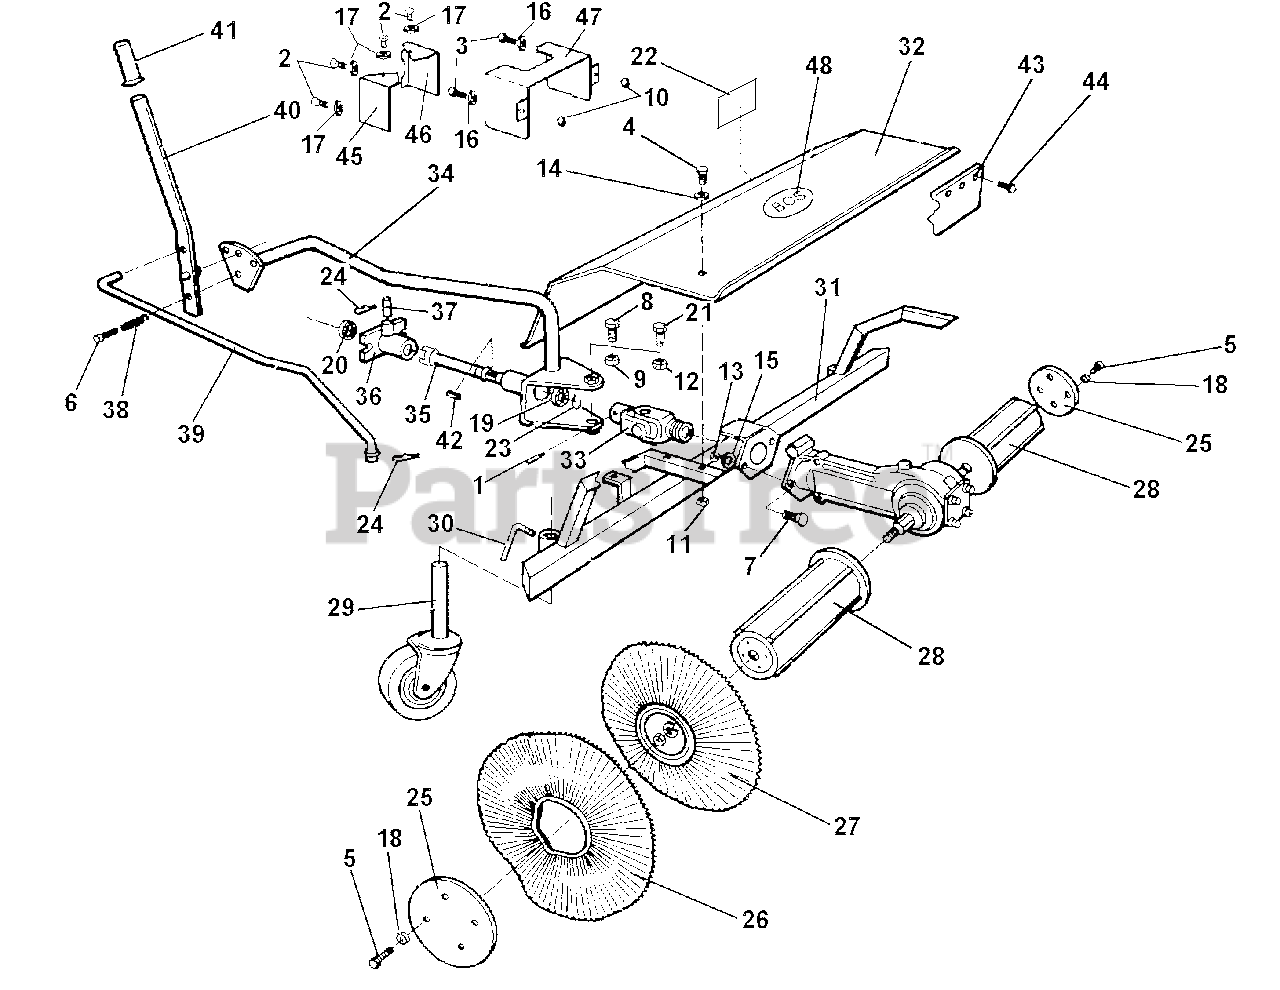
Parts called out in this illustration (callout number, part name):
1	SCREW, M10X10
2	SCREW, TE M6X10
3	SCREW, TE M6X45
4	SCREW, M6X35
5	SCREW M10X30
6	SCREW M10X60
7	SCREW, M12X30
8	SCREW, M16X40 - FOR OLDER SWEEPERS
9	NUT, M16 - FOR OLDER SWEEPERS
10	NUT, SELF LOCKING M6
12	NUT, M10 - NEWER SWEEPERS
13	NUT, M12
14	WASHER, FLAT M6.4
15	WASHER, FLAT M13
16	WASHER FLAT M17
17	WASHER, FLAT 6.4
18	WASHER, LOCK 10.5
19	BEARING, M25X52X15
20	BEARING, M25X47X12
21	SHOLDER SCREW - NEWER SWEEPERS
22	"READ OWNERS MANUAL" DECAL
23	CIRCLIP, EXTERNAL
26	BRUSH, WAVE
27	BRUSH, CONCAVE
29	CASTER WHEEL
30	ADJUSTING SCREW
31	FRAME, SUPPORT
34	BRACE WITH ANGLE PLATE
39	BAR, ANGLE ADJUSTER
40	LEVER, ANGLE ADJUSTER
41	GRIP, RUBBER
48	"BCS" DECAL
